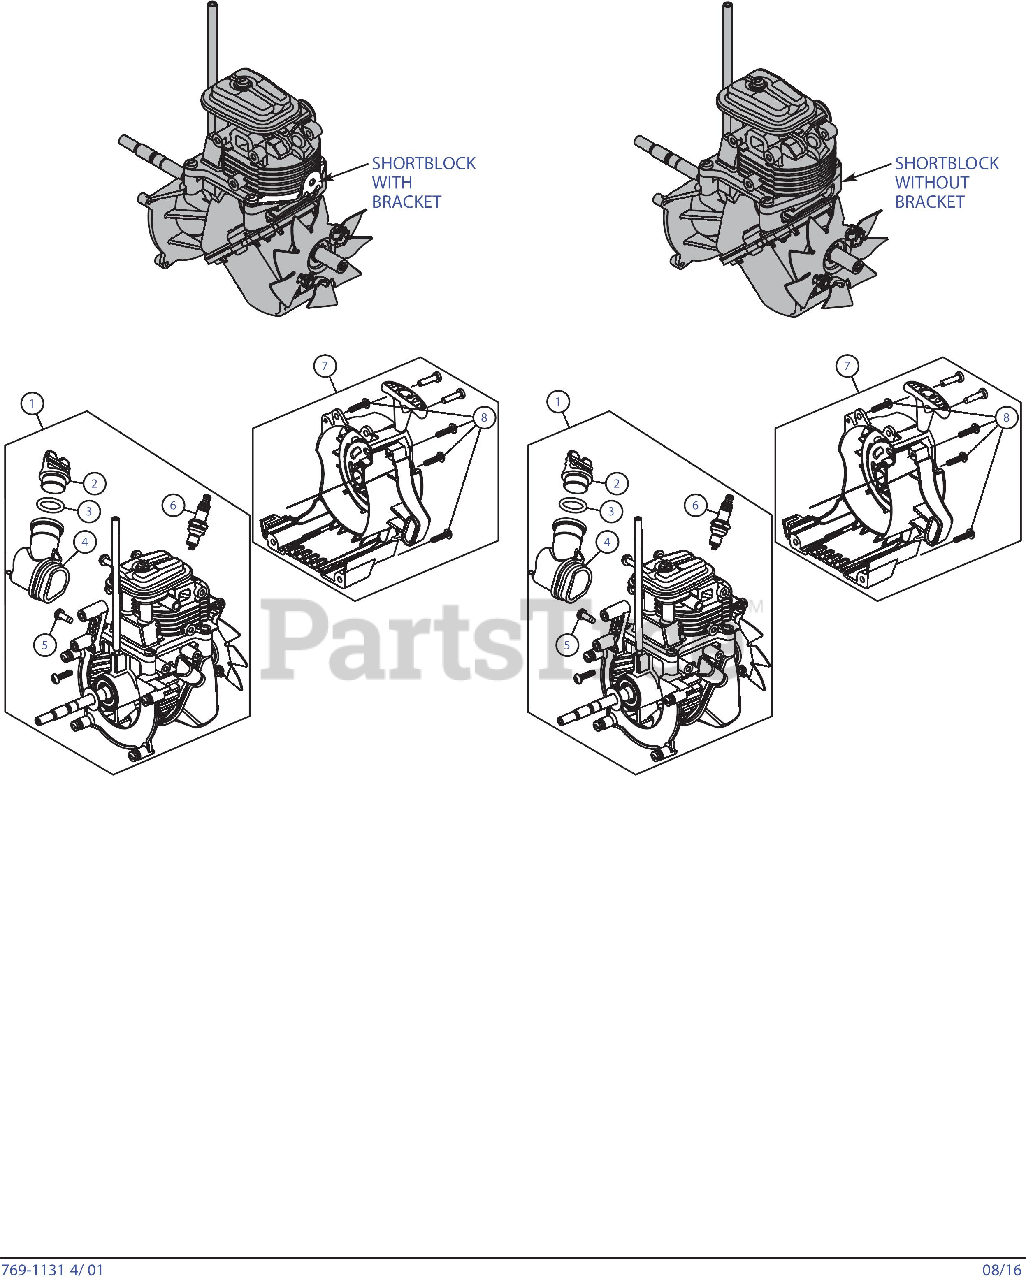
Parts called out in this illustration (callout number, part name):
1	Shortblock Assembly (With Bracket)
1	Shortblock Assembly (Without Bracket)
2	Oil Fill Plug
3	O-Ring
4	Oil Fill Tube
5	Screw
6	Spark Plug
7	Starter Housing Assembly (Incl. 8) (With Bracket)
7	Starter Housing Assembly (Incl. 8) (Without Bracket)
